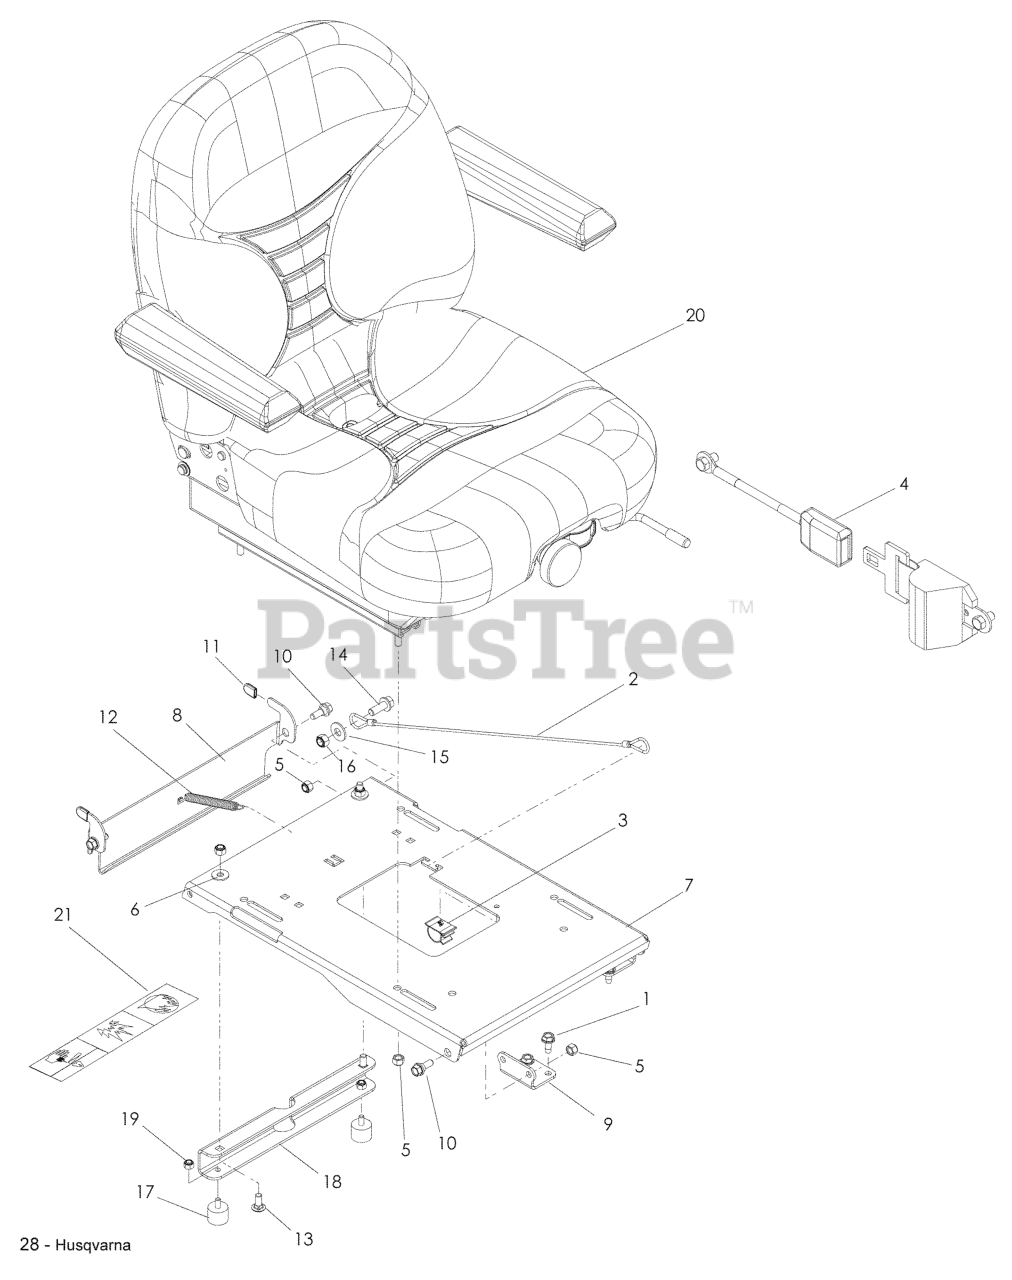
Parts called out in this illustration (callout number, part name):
1	BOLT 5/16-18 X 3/4
2	SEAT LANYARD
3	PUSH-MOUNT WIRE CLIP
4	SEAT BELT, RETRACTABLE
5	NUT 5/16 NYLOC
6	WASHER 5/16 FLAT
7	PAN, SEAT - BLACK
8	LATCH, SEAT - BLACK
9	PIVOT, SEAT PAN
10	SB 5/16-18 HEX HD GD5, BLK ZN
11	GRIP, VINYL, .09 X .495 X.75
13	BOLT 5/16C X 3/4" CARRIAGE
14	4CS 3/8C X 1 SERRATED HEAD
15	WASHER 3/8 FLAT
16	NUT 3/8-16 NYLOC
17	STUD/PLATE MOUNT
18	STANDOFF, SEAT PAN
19	NUT.1/4-20.HEX.NYLOC.ZD
20	SEAT - SUSP, NC SWITCH
21	EURO DECAL-BATTERY WARNIN6
